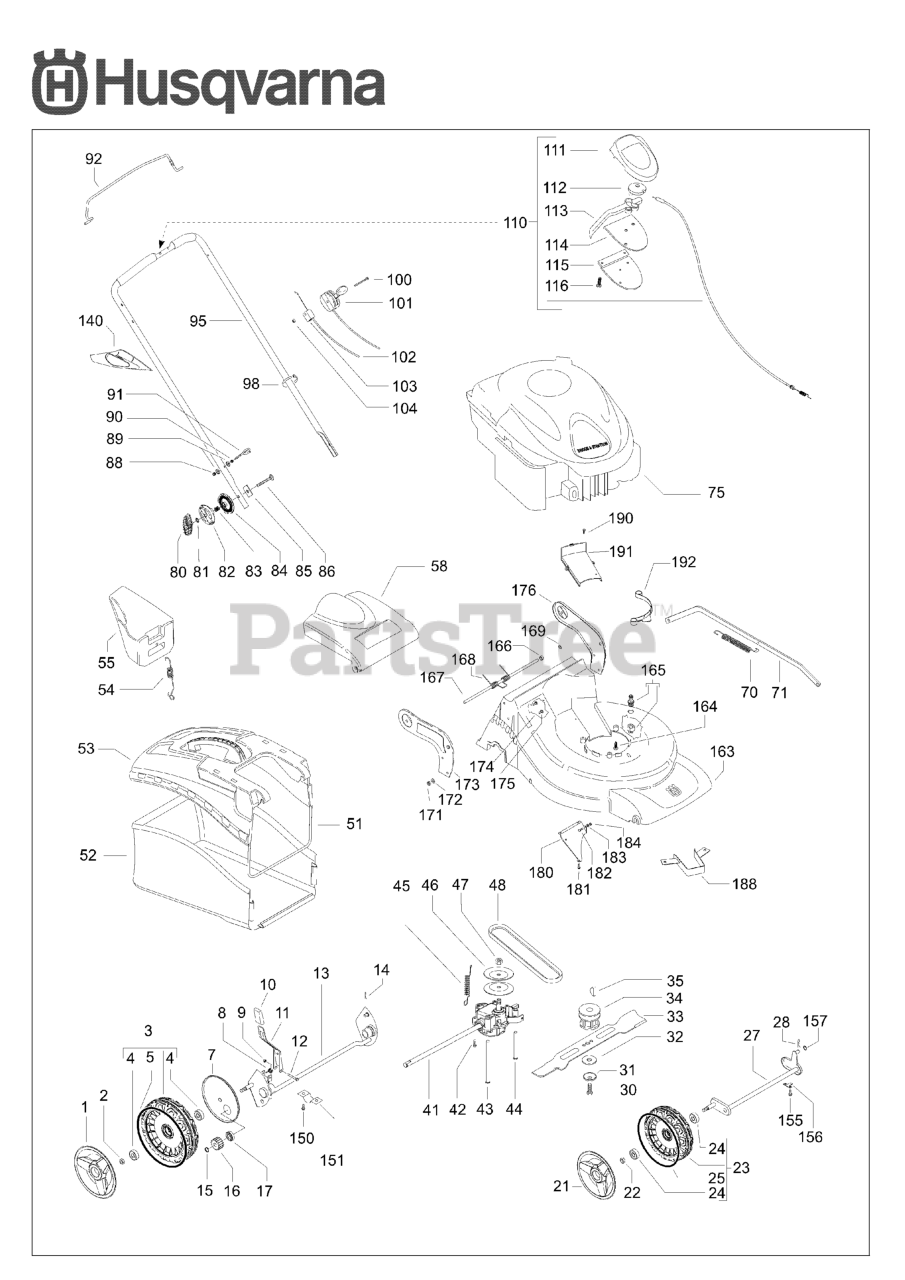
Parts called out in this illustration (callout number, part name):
188	Screws
209	Springs
222A	Brackets
267	Screws
268	Casing
269	Wires
270	Nuts
333	Ignition Module
337	Spark Plugs
505	Nuts
562	Bolts
635	Spark Plugs
745	Screws
745A	Screws
